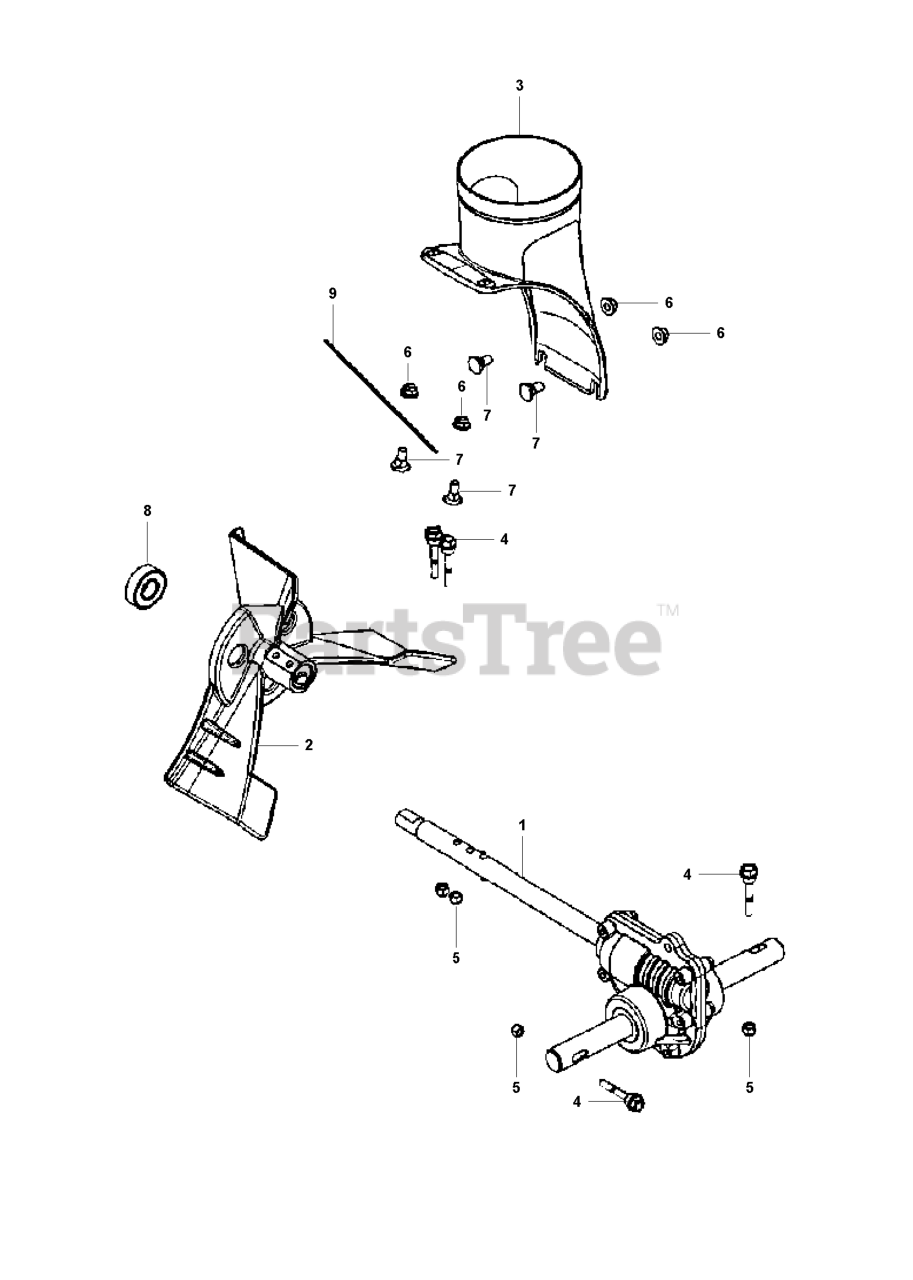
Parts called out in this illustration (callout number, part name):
1	GEARBOX CAST DD SHAFT
3	CHUTE BASE CAST ALUM HUSQ SIL
4	BOLT SHEAR HX HD 1/4-20 CLEAR
5	NUT HEXAGON 1/4-20 ST ZPB
6	NUT HEX FLG NYLOCK BLK 5_16-1
7	BOLT CARR WAFER BLK 5_16-18 X
